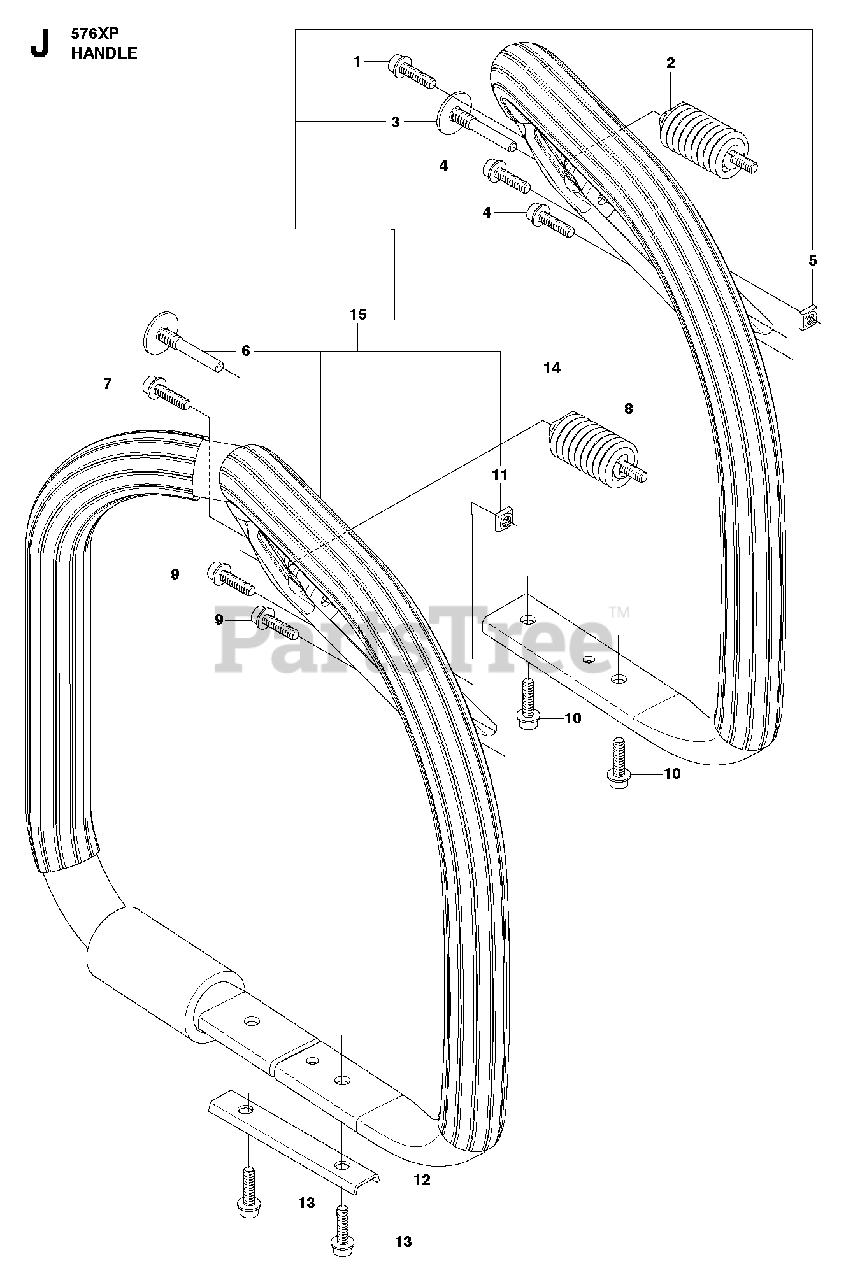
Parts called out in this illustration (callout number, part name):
2	ANTIVIBE MOUNT
3	SCREW
5	NUT
6	SCREW
8	ANTIVIBE MOUNT
11	NUT
14	%FRONT HANDLE
14	FRONT HANDLE ASSY
15	HANDLE
